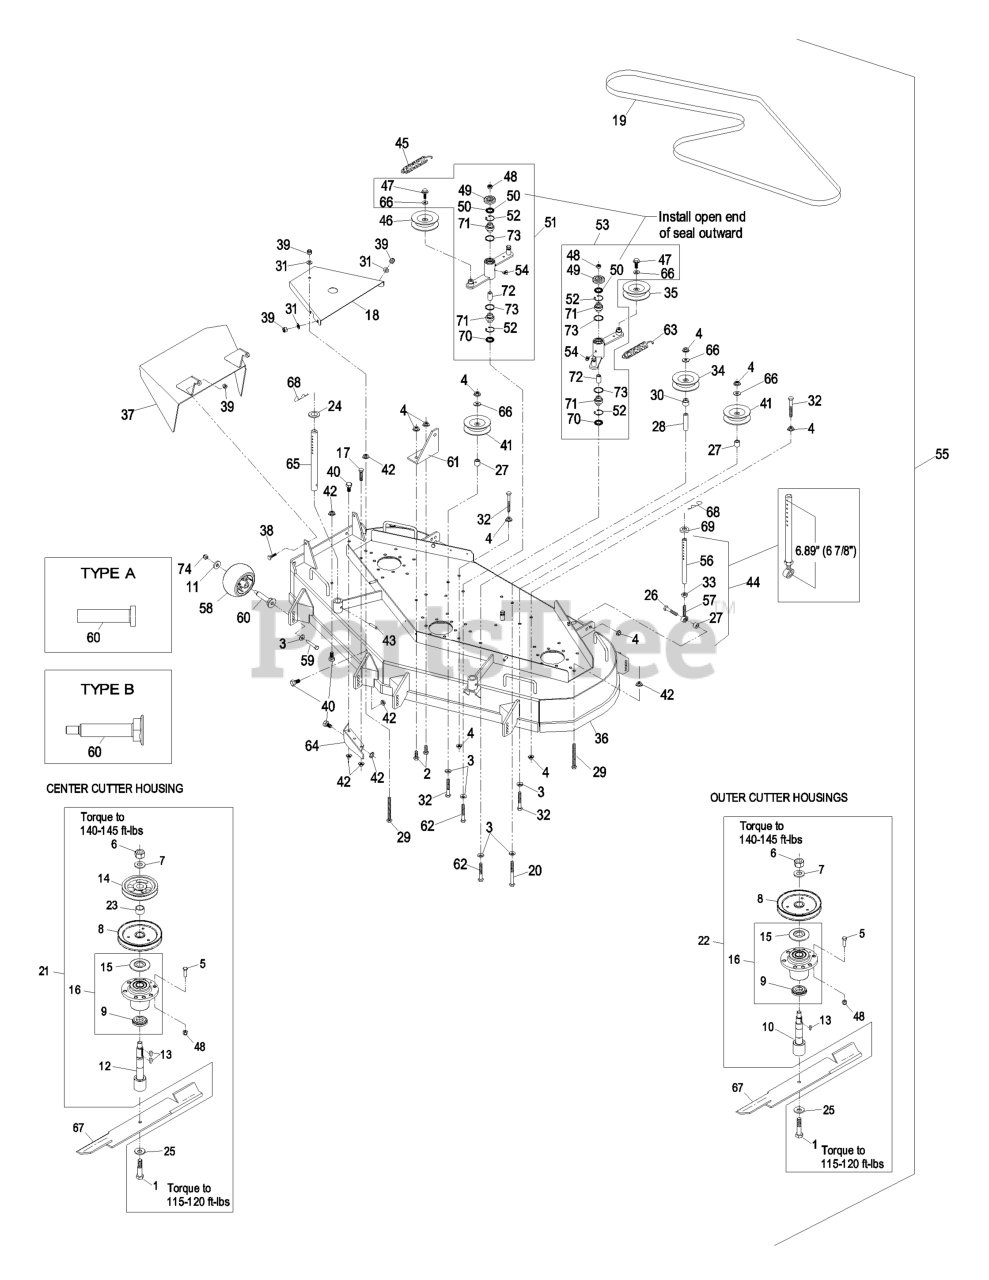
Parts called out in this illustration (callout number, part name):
1	SCREW-CAP
2	SCREW-HH
3	WASHER-BELLEVILLE
4	NUT-HHF, WHIZ
5	SCREW-HH
6	NUT-HH
8	SHEAVE,BLADE DRIVE 6.30
9	SPACER-GUARD, BOTTOM
10	SPINDLE,SHORT
12	SPINDLE,LONG
14	SHEAVE,MOWER DRIVE
15	GUARD-BEARING, TOP
16	KIT, CUTTER HOUSING
17	SCREW-HH
18	SHIELD,BELT SIDE FMD524
19	BELT,BLADE DRIVE FMD524
20	SCREW-HH
22	ASM, CUTTER HSG COMPLETE
23	SPACER,TUBE
24	SPACER-DECK SUPPORT
25	WASHER-BLADE BOLT, HEAVY
26	SCREW-HH
28	SPACER-ANCHOR, CLUTCH
29	BOLT,TAP HH
30	BUSHING,IDLER
31	WASHER-FLAT
32	BOLT-CARR
33	NUT-HEX
34	PULLEY-IDLER
35	PULLEY-IDLER
37	WLD,CHUTE FMD524
38	SCREW-HH
39	NUT-LOCK, NI
40	SCREW-HH
41	IDLER,PULLEY
45	SPRING-EXTENSION
46	IDLER,PULLEY
47	SCREW-HHF
48	NUT-LOCK, NI
49	GUARD-TOP
50	SEAL-LIP, SINGLE
51	KIT, IDLER ARM W/BEARINGS
52	RING-SNAP
53	KIT, IDLER ARM W/BEARINGS
54	FITTING-GREASE, 90 DEG
55	Complete Deck Assembly
56	LINK,SUPPORT
57	BALLJOINT
58	ROLLER-SCALP, ANTI
59	SCREW-HH
60	BUSHING-ROLLER
61	BRACKET,SPRING ANCHOR
62	SCREW-HH
63	SPRING-EXTENSION
64	WLD,BAFFLE DISCHARGE
65	ROD,DECK SUPPORT
66	WASHER-FLAT
68	PIN,HAIR COTTER
70	SEAL-LIP, DOUBLE
71	BEARING-SPHERICAL
72	BUSHING-LEVER, LIFT
74	NUT-HHF, WHIZ
